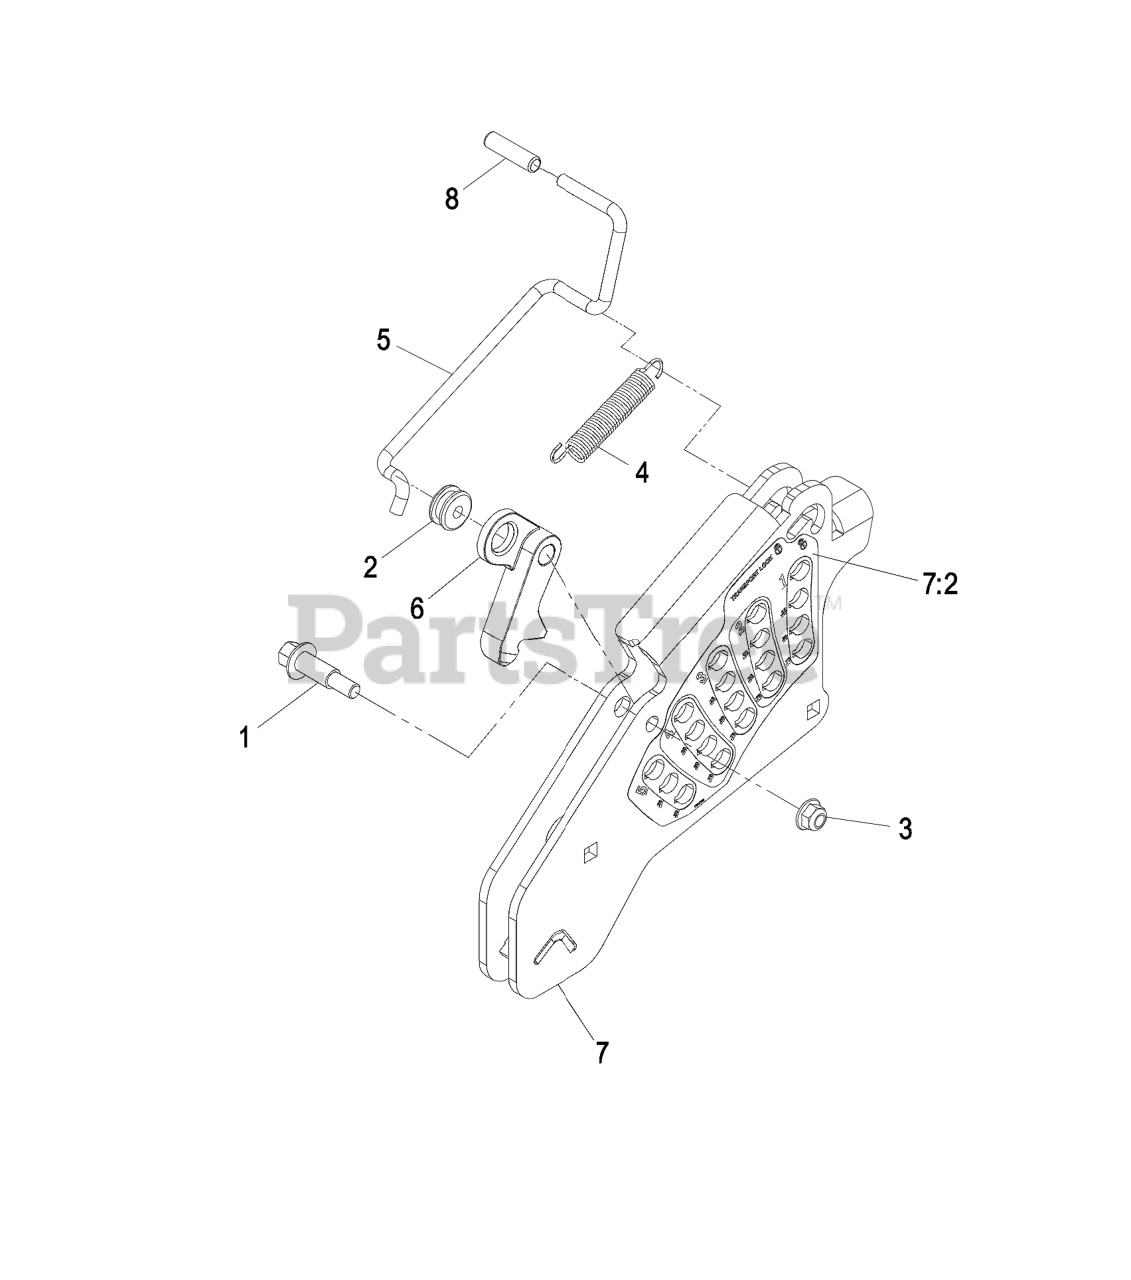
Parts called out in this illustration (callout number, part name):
1	BOLT-SHOULDER
2	GROMMET
3	NUT-HF, NI
4	SPRING-EXTENSION
5	ROD-LOCK, TRANSPORT
6	PAWL-TRANSPORT, HOC
7	HOC PLATE ASM
7:2	DECAL-HOC
8	GRIP-LEVER
